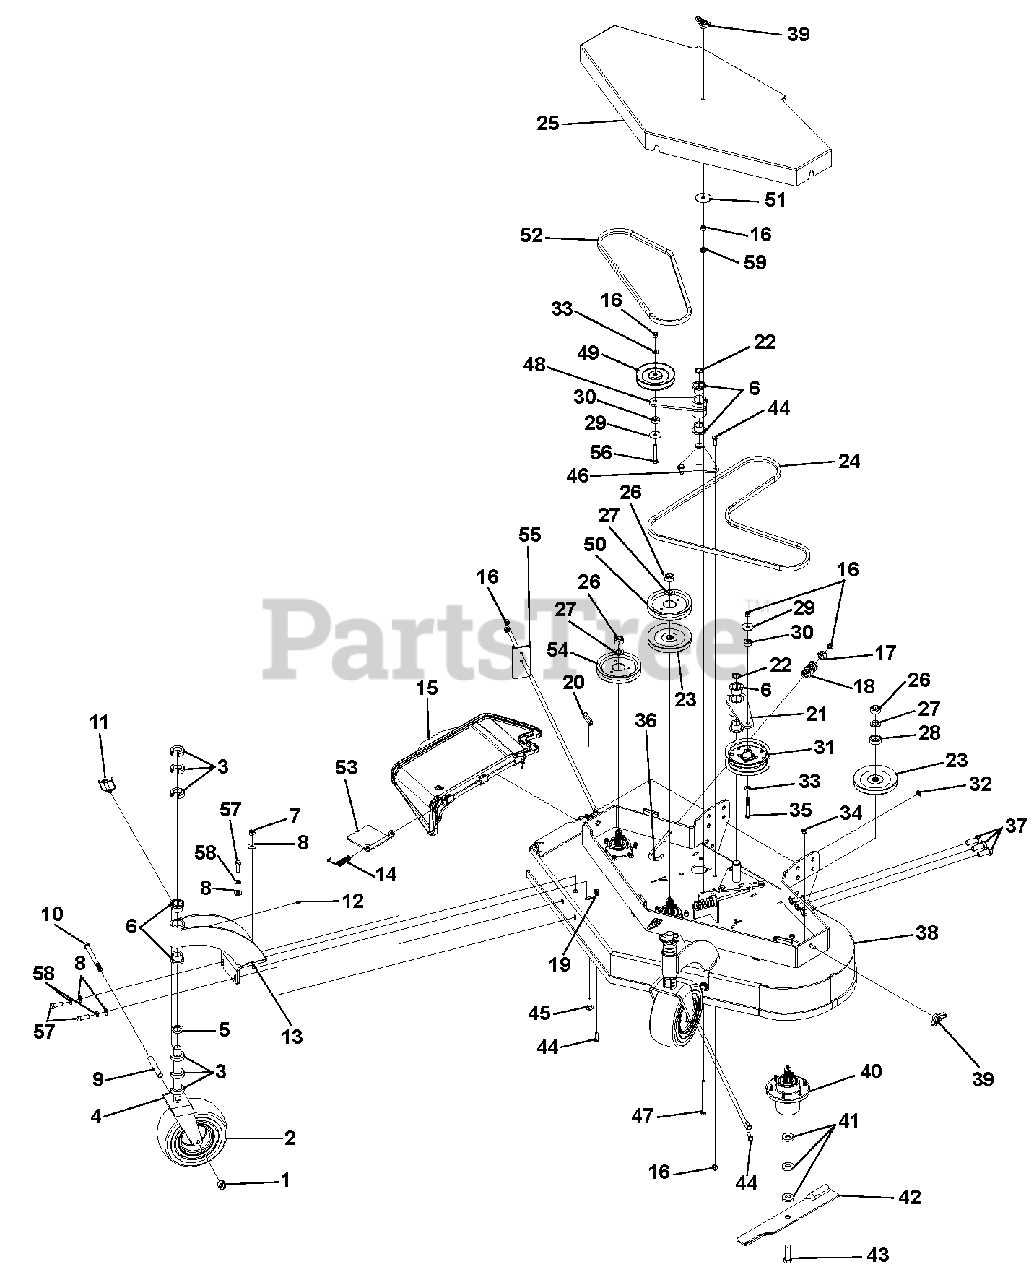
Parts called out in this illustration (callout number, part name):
1	Locknut, .50-13 Nyloc
2	Assembly, Wheel and Tire 9 x 3.5
3	C-Spacer, 1.00 x 1.77 x .500
4	Weldment, Caster Yoke w/Gravely Paint
5	Bushing, 1.03 x 1.50 x .179
6	Bearing, Flange 1.00 x 1.25 x 1.00
7	Locknut, .4375-14 Crown
8	Washer, .375 Regular Flat
9	Tube, Caster Axle
10	Bolt, .50-13 x 5.50 Hex 5
11	Pin, LNC .438 x 2.00
12	Fitting, .25-28 STRGT Grease Zerk
13	Weldment, Caster SUPP w/Gravely Paint
14	Spring, Torsion .460 x .138
15	Chute Discharge Assembly
16	Locknut, .38-16 Nyloc
17	Keeper, Spring
18	Spring, COM 1.22 x .162 x 2.50
19	Locknut, .38-16 Crown
20	Trim, 1/4" Trim-LOK
21	Weldment, Idler Arm
22	Snap Ring, 1.00 x .042 External
23	Pulley, Narrow Spline
24	Belt, HB Wrapped CARLISLE
25	Weldment, 48" Belt Shield Gravely
26	Locknut, .75-16 Crown
27	Washer, .75 x 1.3125 x .120
28	Spacer, Spindle Top-Pulley
29	Washer, Flat .375 x 1.50 x .063
30	Bushing, .380 x 1.00 x .410
31	Pulley, Flat 5.00 x .375 W/BRG
32	Retainer
33	Washer, .406 x .813 x .065 Flat
34	Nut, .38-16 Standard Hex Grade 5
35	Bolt, .38-16 x 2.75 Hex 5
36	J-Bolt, .38-16 x 7.88
37	Bolt, Hex .625-11 1.5 Grade 8
38	48" Gravely Gear Deck with Decals
39	Knob, .38-16 Insert
40	Assembly, Spindle Housing
41	Washer, .630 x 1.50 x .250 Flat
42	Blade, 16.500 x .80 Lift
43	Bolt, .625-11 x 2.00 Hex 8
44	Bolt, .38-16 x 1.00 Hex 5
45	Bolt, .4375-14 x 1.25 CRG 5
46	Weldment, Idler Pivot Mount
47	Bolt, .38-16 x 5.00 Tapping
48	Weldment, Idler Arm
49	Pulley, Idler 5.0 V-GROOVE
50	Spline, Spindle Pulley Offset
51	Washer, .402 x 2.00 x .055
52	Belt, HB 51.4 Elbow AMD
53	Bracket, Chute Support
54	Pulley, Spline Spindle LSE
55	Plate, Extender
56	Bolt, .38-16 x 2.50 Hex 5
57	Bolt, .4375-14 x 1.25 Hex 5
58	Washer, .438 Medium Spring Lock
59	Locknut, .38-16 Whiz
